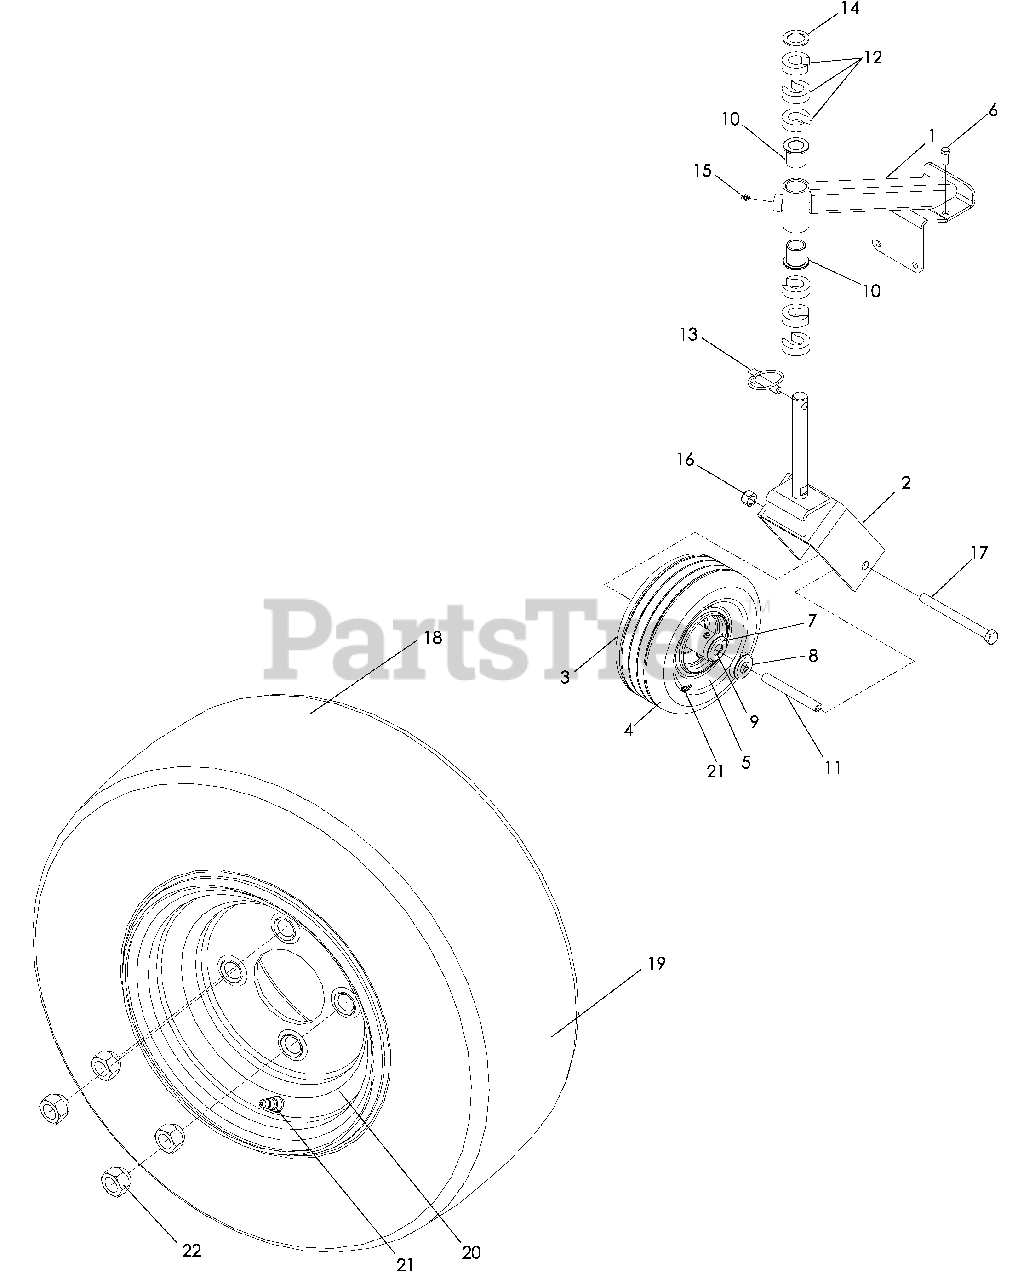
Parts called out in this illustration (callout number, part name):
1	CASTER ARM W/BUSHINGS
2	CASTER FORK
3	WHEEL ASSEMBLY, CASTER
4	TIRE, CASTER
6	HCS, 3/8-16 x 1
7	ENDCAP
8	NOTCHED ENDCAP
9	ROLLER BEARING
10	BUSHING, FLANGED
12	"C" SPACER
13	LYNCH PIN, 7/16
15	ZERK
16	NUT ½ HEX NYLOC
17	HCS, ½-13 x 5½
18	WHEEL ASSEMBLY, REAR
19	TIRE, REAR
22	NUT, LUG ½
